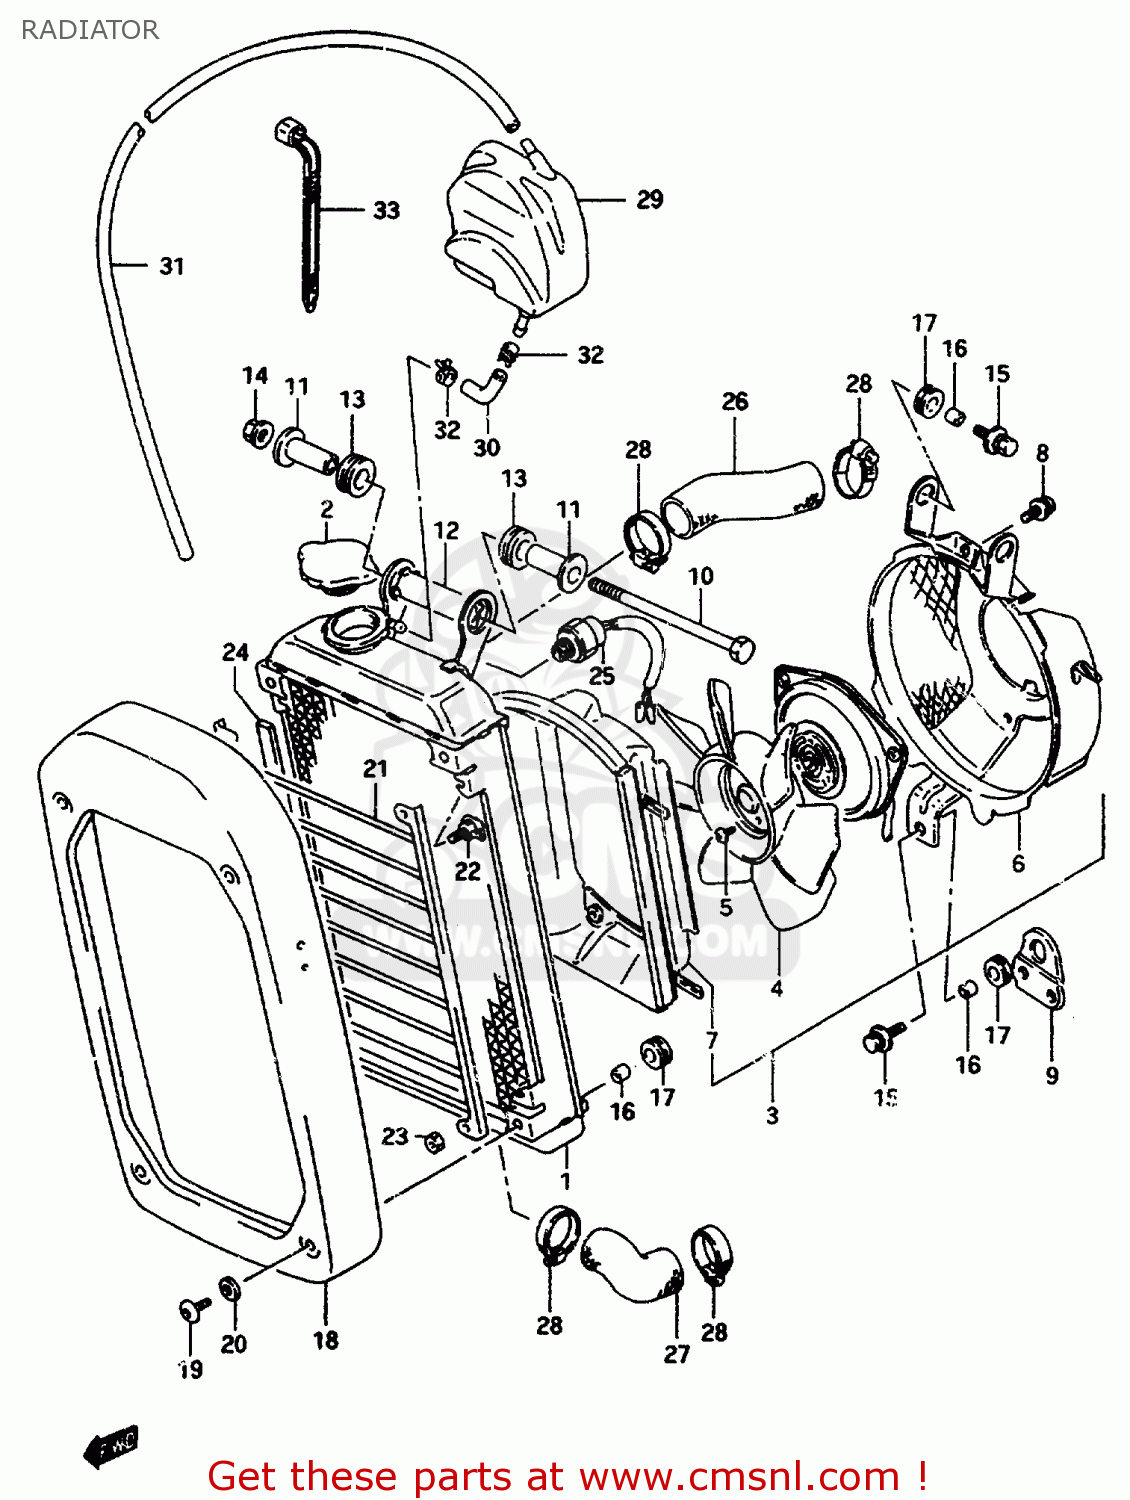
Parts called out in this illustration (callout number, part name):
1	RADIATOR COMP,WATER
2	CAP,RADIATOR
3	FAN ASSY,RADIATOR
4	FAN
5	SCREW 4X6
6	SHROUD,FAN
7	DUCT,FAN
8	SCREW
9	BRACKET,RADIATOR FAN
10	BOLT(10X135)
11	SPACER,RADIATOR CUSHION NO.2
12	SPACER,RDTR CUSH NO.2 OUTER
13	CUSHION
14	NUT 10MM
15	BOLT
16	SPACER (6X9X8)
17	CUSHION
18	COVER,RADIATOR
19	SCREW(6X10)
20	WASHER (6.2X14X2)
21	BUMPER COMP,RADIATOR
22	BOLT
23	NUT
24	CUSHION,RADIATOR BUMPER
25	SWITCH,RADIATOR FAN
26	HOSE,RADIATOR INLET
27	HOSE,WATER PUMP OUTLET
28	CLAMP
29	TANK,RESERVOIR
30	HOSE,RESERVE TANK INLET
31	HOSE,RESERVOIR TANK OUTLET
32	CLIP
33	CLAMP(L:125)
